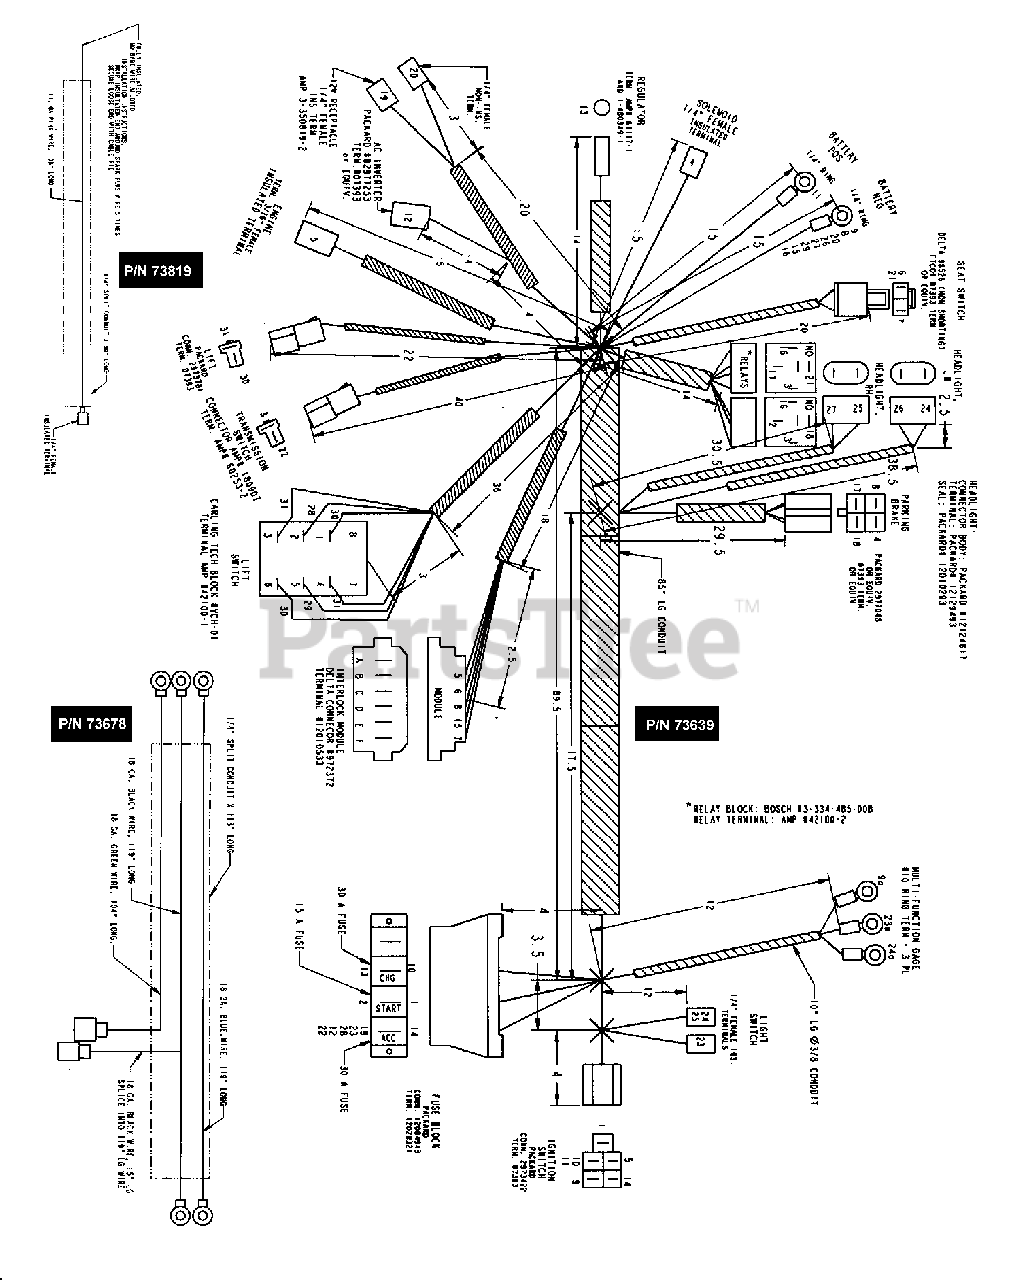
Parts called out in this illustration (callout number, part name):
1	WIRING HARNESS, Main
2	WIRING HARNESS, Speed/Fuel
3	WIRING HARNESS, Tachometer
